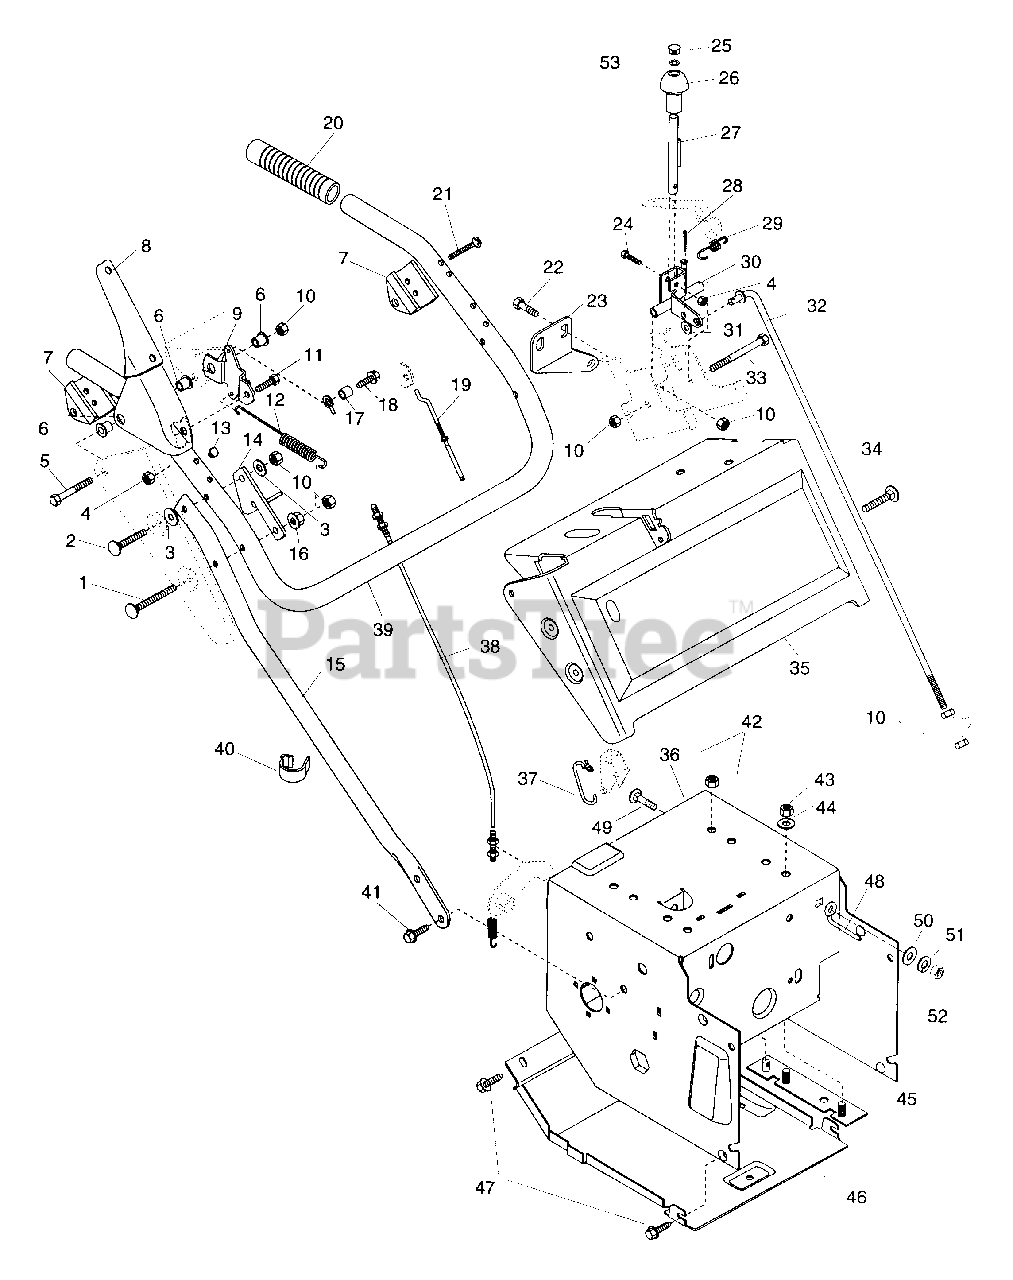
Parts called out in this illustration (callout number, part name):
1	BLT-RDHDSQNK .31-18X2.75 SHPL
2	BLT-RDHDSQNK .31-18X1.50 PL
3	WSHR-FL-STL .438X1.0X.083 PL
4	NUT-LK-CTR .250-20 PL
5	BLT-HEX .31-18X2.50 PL GR2
6	BSHG-FLG .325X.465X.333X.685
7	HANDLE PIVOT
8	CLUTCH LEVER - COATED
10	NUT-LK .312-18 GR A PL
11	BLT-HEX .25-20X.38 PL GR2
12	SG-TENS .051X.50X5.12 WLD 10.4
14	UPPER CABLE ANCHOR R H
15	L H LOWER HANDLEBAR
16	NUT-FLG. .312-18 PL
17	SPACER .230X.310X.255
18	SCR-TAP 12-24X.50 HWH PL TR
19	CABLE, ADJUSTABLE
20	HANDLE GRIP
21	SCR-TAP 12-14X1.50 CROVH PL BT
22	BLT-HEX .31-18X.50 PL GR2
23	CHUTE CRANK BRACKET
24	BLT-HEX .25-20X1.00 GR2
25	HOLE PLUG
27	ROD
28	PIN-COTR .09X.75 PL
29	SG-TENS .055X.33X1.31 WLD 7
31	WSHR-FL-STL .323X.625X.062 PL
32	SHIFT ROD
33	BLT-HEX .31-18X3.50 PL GR2
34	BLT-RDHDSQNK .31-18X1.75 SHTPL
35	PANEL W/DECAL
36	FRAME
38	CLUTCH CABLE-ATTACHMENT
39	UPPER HANDLEBAR
41	BLT-SERHFWH .31-18X.62 PL
42	NUT-LK-NYL.312-18 PL
43	NUT-HEX .312-18
44	WSHR-LK .312X.097 PL HVY
45	ENGINE MOUNT, 5L,7L,8R
46	COVER-BOTTOM
47	SCR-TAP .250-20X.37 HWH PL TR
48	HOUSING, BLOWER - 24"
49	@BLT-RDHDSQNK .31-18X1.00 G5YZ
50	@WSHR-FL-STL.38X.875X.083 YWZC
51	@WSHR-LK .31X.078 REG YWZC
52	@NUT-HEX .31-18 YWZC
53	RG-RTNG-EXT .500X.015
